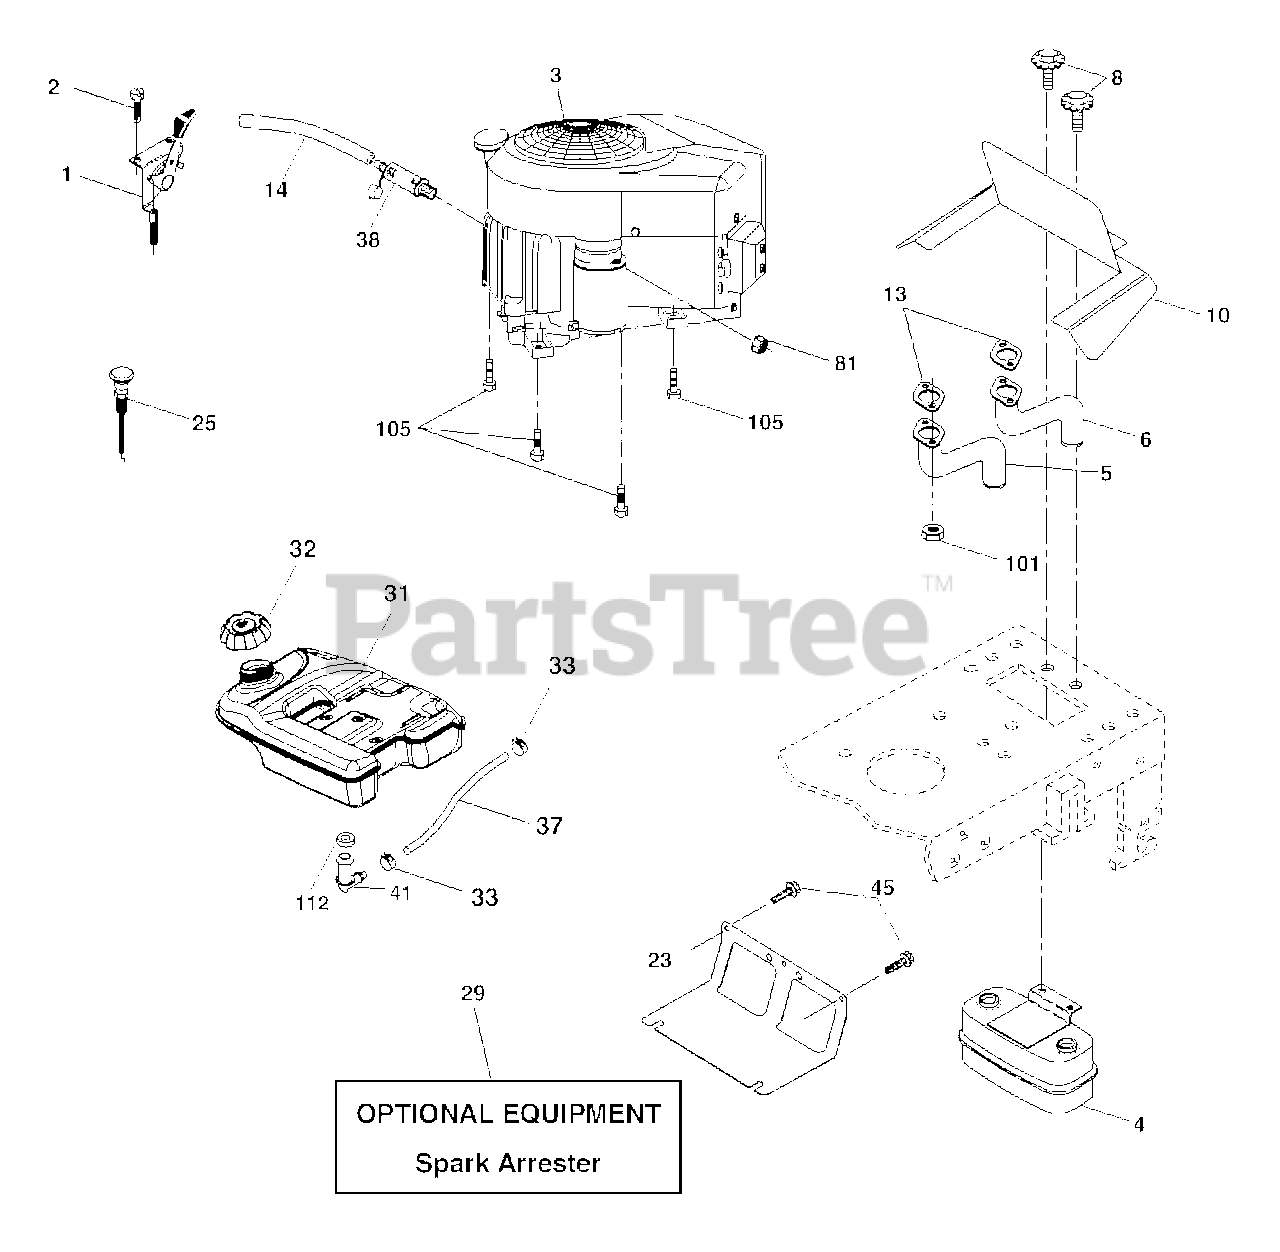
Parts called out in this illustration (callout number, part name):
1	Control, Throttle
2	Screw Hex Thd Cut 1/4-20 x 1/2
5	Exhaust Tube LH
6	Exhaust Tube RH
8	Bolt 5/16-18 unc x 3/4 w/Sems
10	Shield Heat Muffler
13	Muffler Gasket
14	Tube Oil Drain
23	Shield, Browning/Debris Guard
25	Control Choke
29	Arrester, Spark
31	Tank, Fuel
32	Cap Gauge, Fuel
33	Clamp, Hose Blk
37	Line, Fuel
38	Plug Drain Oil Easy
41	Stem Tank Fuel
45	Screw Hex Wsh Thdrol 3/8-16 x 3/4
81	Nut Keps Hex 1/4-20 unc
101	Nut Flange Toplock M8-1.25
105	Screw 3/8-16 x 1
112	Bushing
